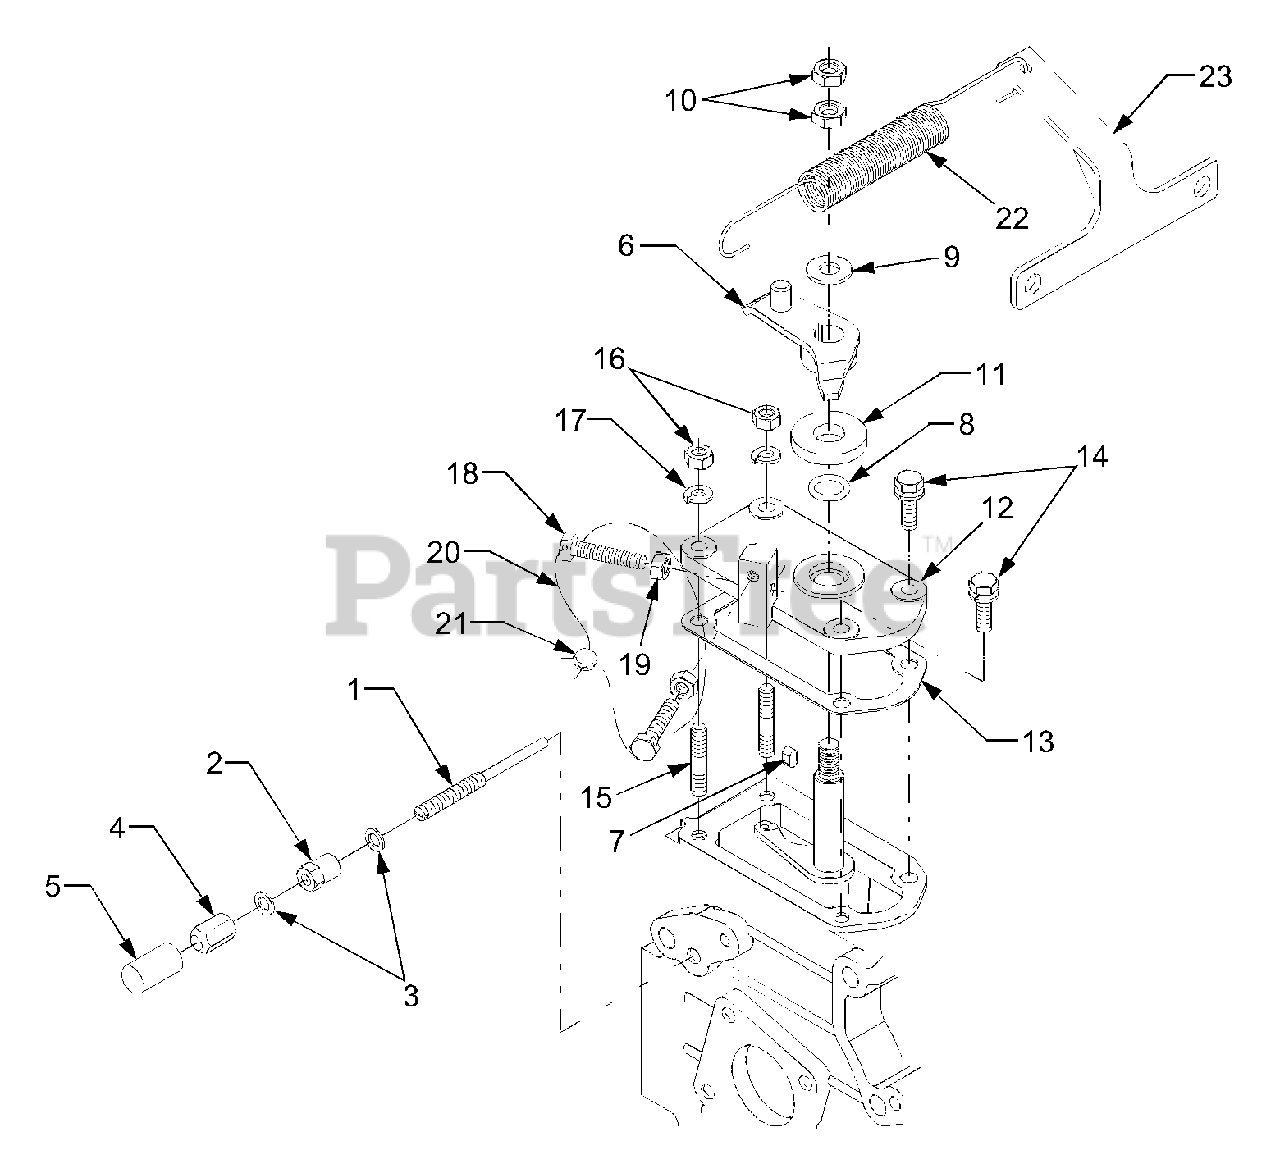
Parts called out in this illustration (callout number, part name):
1	Bolt, Adjusting
6	Lever, Speed Control
9	Washer, Plain
11	Plate, Friction
12	Plate, Speed Control
13	Gasket, Control Plate
17	Washer, Spring
21	Lead, Sealing
23	Support, Spring
